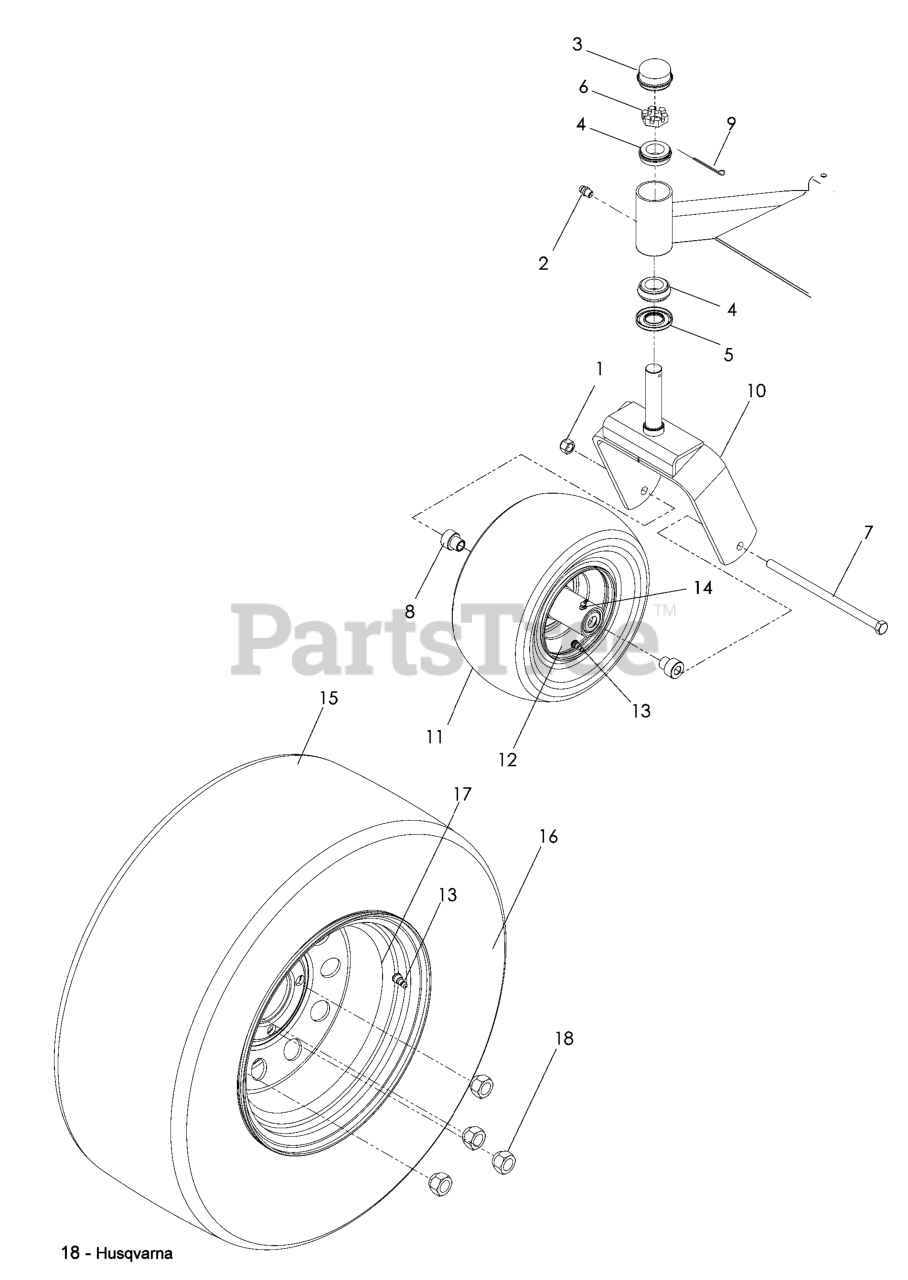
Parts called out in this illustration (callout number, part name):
1	NUT 1/2-13 HEX NYLOC ZD
2	ZERK
3	GREASE CAP
4	TAPERED ROLLER BRG
6	NUT 1"C HEX SLOTTED
7	HEX SCREW 1/2-13 X 9.5 GR5
8	AXLE SPACER
9	COTTER PIN 1/8 X 2
10	CASTOR YOKE ORANGE
11	FRONT TIRE ASSY
13	VALVE STEM TR-412
14	ZERK
15	WHEEL/TIRE.ASM.24X12-12.SILVER
16	TIRE.24X12-12.TURF.MASTER
17	12"RIM 2.5" NEG OFFSET 8.5" W
18	LUG NUT 1/2F
